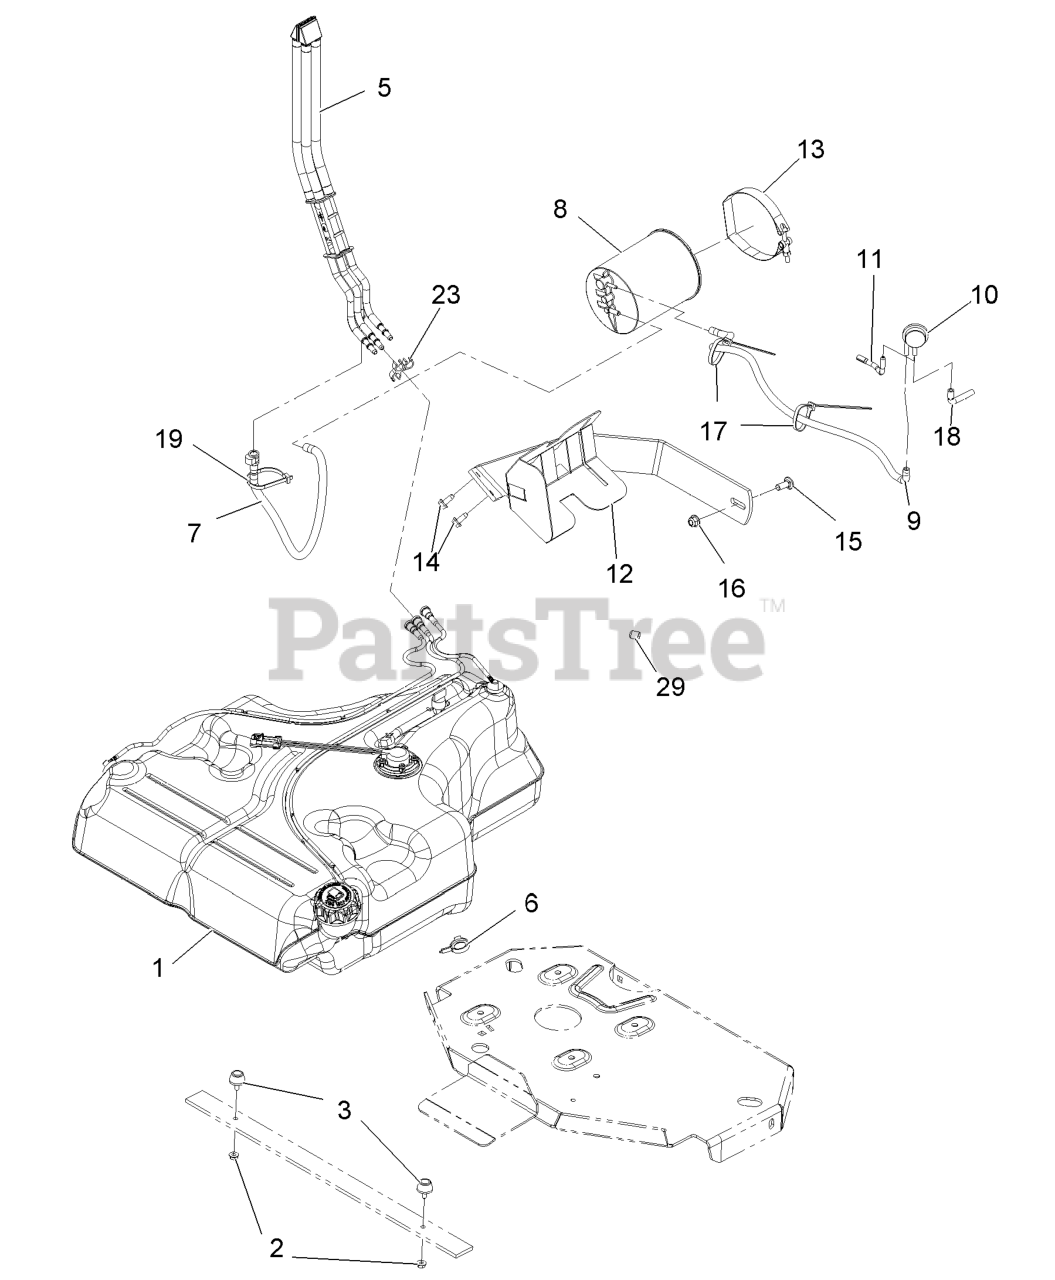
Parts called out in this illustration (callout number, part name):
3	BUMPER-RUBBER
5	FUEL MANIFOLD VENT ASM
6	CLAMP-HOSE
7	VENT HOSE ASM
8	CANISTER-CARBON, 1200CC
9	HOSE-VENT, FORMED
10	VALVE-CONTROL, VACUUM
11	HOSE-VENT, FORMED
12	MOUNT-CANISTER
13	CLAMP, T-BOLT
14	Screw-HWH 5/16-18 X 3/4 Tf
15	SCREW-CARR
16	NUT-HF, NI
17	TIE-PLASTIC
18	HOSE-VENT, FORMED
19	TIE-PLASTIC
23	CLIP-SPACER
29	PLUG-PORT
